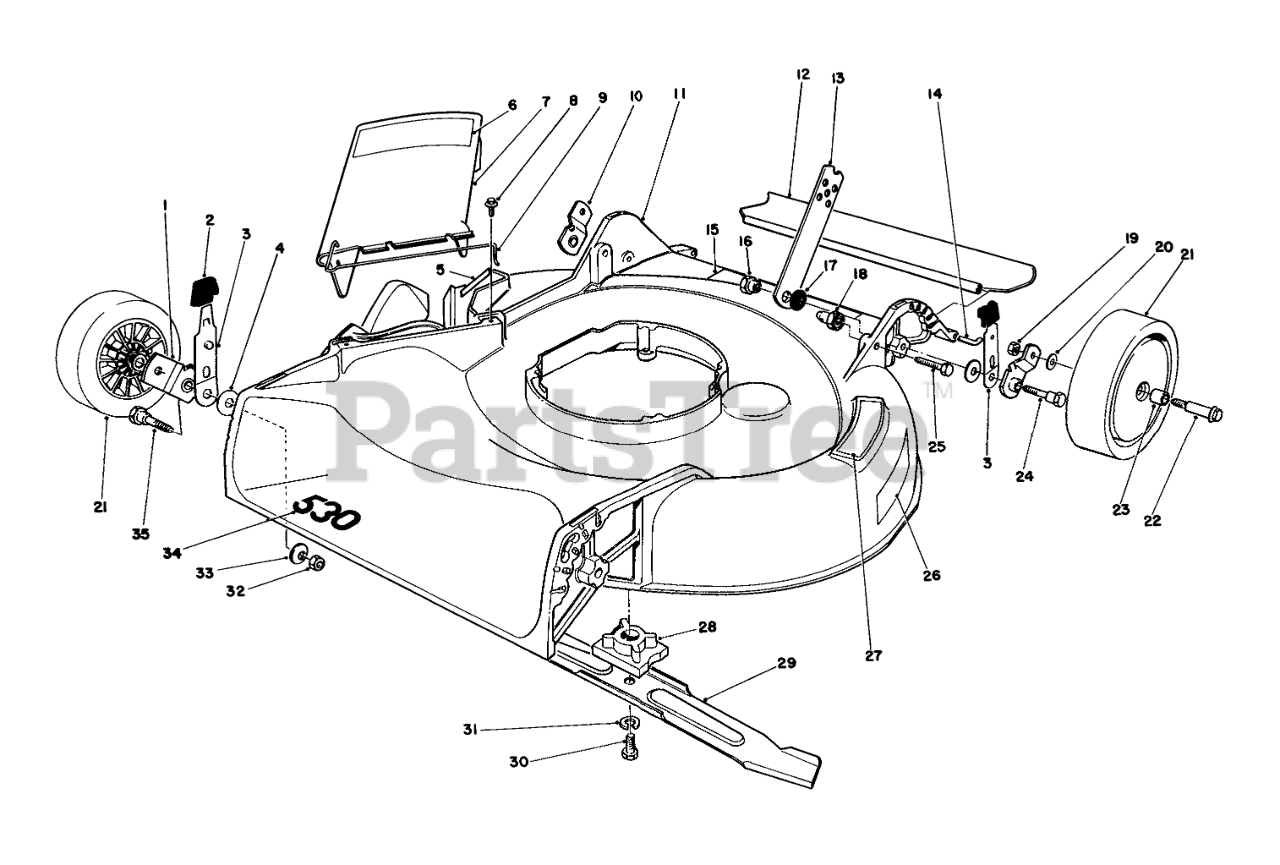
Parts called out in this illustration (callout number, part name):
1	Pivot Arm
2	KNOB-ARM
3	SPRING ARM ASM
4	WASHER-PIVOT
5	Decal-Danger
6	DANGER DECAL
7	Deflector Assembly (Incl Ref. #689)
8	SCREW-HWH
9	SPRING HINGE
10	Pivot Arm
11	HOUSING/DECAL
12	REAR SAFETY SHIELD 21
13	HANDLE LATCH
14	SHIELD ROD
15	DECAL-DANGER
16	HANDLE PIVOT NUT
17	SPACER
18	HANDLE PIVOT NUT
19	NUT-LOCK
20	WASHER
21	Wheel 8 Tire Assembly (Incl. Ref. #23)
22	WHEEL BOLT
23	BUSHING
24	PIVOT SCREW
25	SCREW-HH
26	Decal-Place Foot Here
27	STEP PAD DECAL
28	BLADE RETAINER
29	Blade
30	SCREW-HH
31	WASHER-LOCK
32	NUT-LOCK, NI
33	WASHER-BELLEVILLE
34	Decal-530
35	PIVOT SCREW
